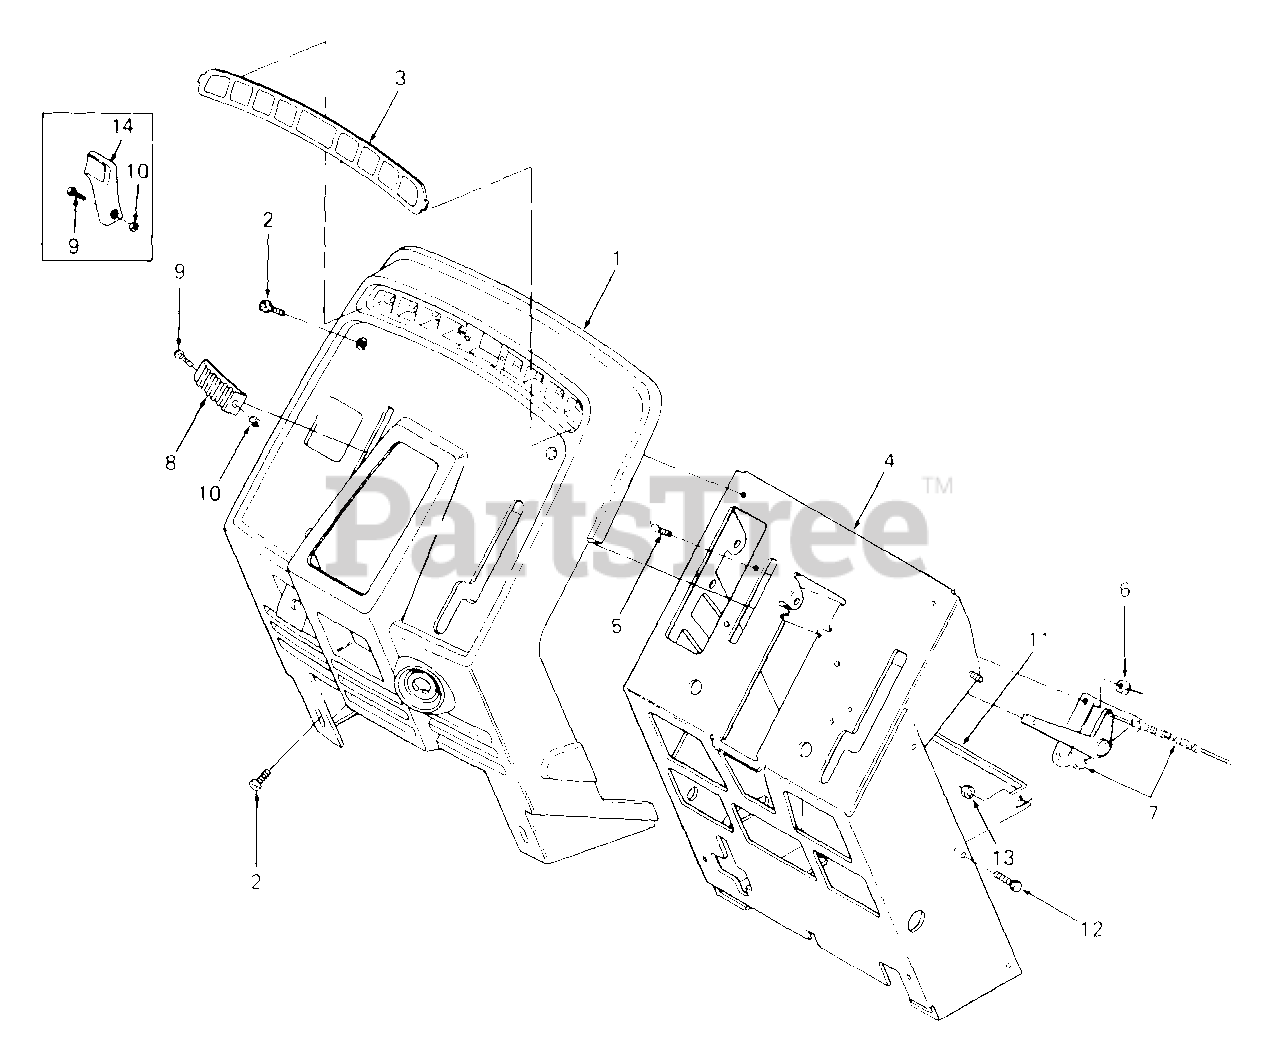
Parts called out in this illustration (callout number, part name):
1	Panel, Instrument
2	Screw, Pan Hd Cutting, #10-24 X .75 Lg
3	Label, Dash
6	Nut, Hex Keps, #10-32
7	Control, Throttle
8	Knob, Throttle
9	Screw, Cross Rec Truss Hd, #8-32 X .38 Lg
10	Nut, 8-32
11	Bracket, Harness
12	Screw, Hex Cap, 1/4-20 X .50 Lg GR5
13	Nut, Hex Patch Lock, 1/4-20
14	Knob, Throttle
